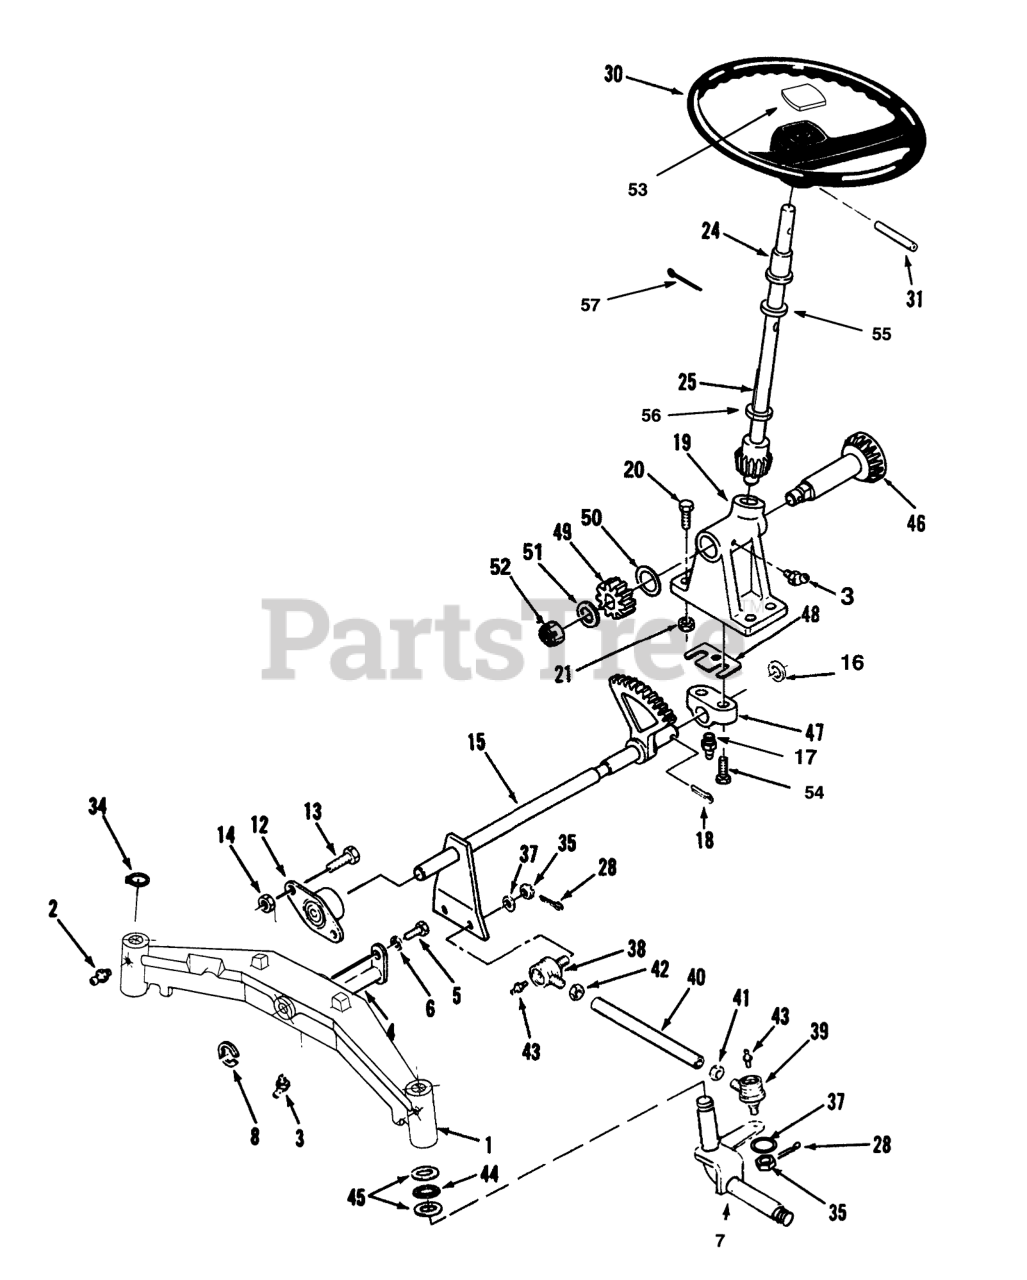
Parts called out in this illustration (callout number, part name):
1	Axle-Front
2	FITTING-GREASE
3	FITTING-GREASE
4	PIN AND PLATE ASM
5	SCREW-HH
6	WASHER-LOCK
7	Spindle
8	E-RING
12	BEARING-FLANGED
13	SCREW-HH
14	NUT-LOCK, NI
15	Shaft
16	Washer
17	ZERK FITTING
18	PIN-COTTER
19	Steering Support
20	SCREW-HH
21	NUT-LOCK, NI
24	BEARING-FLANGED
25	WLDMT-STRG SHAFT
28	PIN-COTTER
30	Steering Wheel (Incl. Ref. #53)
31	PIN-ROLL
34	RING-RETAINING
37	WASHER
38	Tie Rod End-Thread RH (Incl. Ref. #35)
39	Tie Rod End-Thread LH (Incl. Ref. #35)
40	Tube
41	NUT-HEX JAM 9/16-18
42	NUT-JAM
43	FITTING-GREASE
44	BEARING-THRUST
45	WASHER-THRUST
46	WLDMT-C SHAFT
47	BLOCK-BEARING
48	SHIM-.010
49	PINION-SPUR
50	Washer
51	WASHER-FLAT
52	Nut
53	STRG-WHL INSERT TORO
54	Bolt
55	WASHER-SHIM
56	O-RING
57	PIN-COTTER
